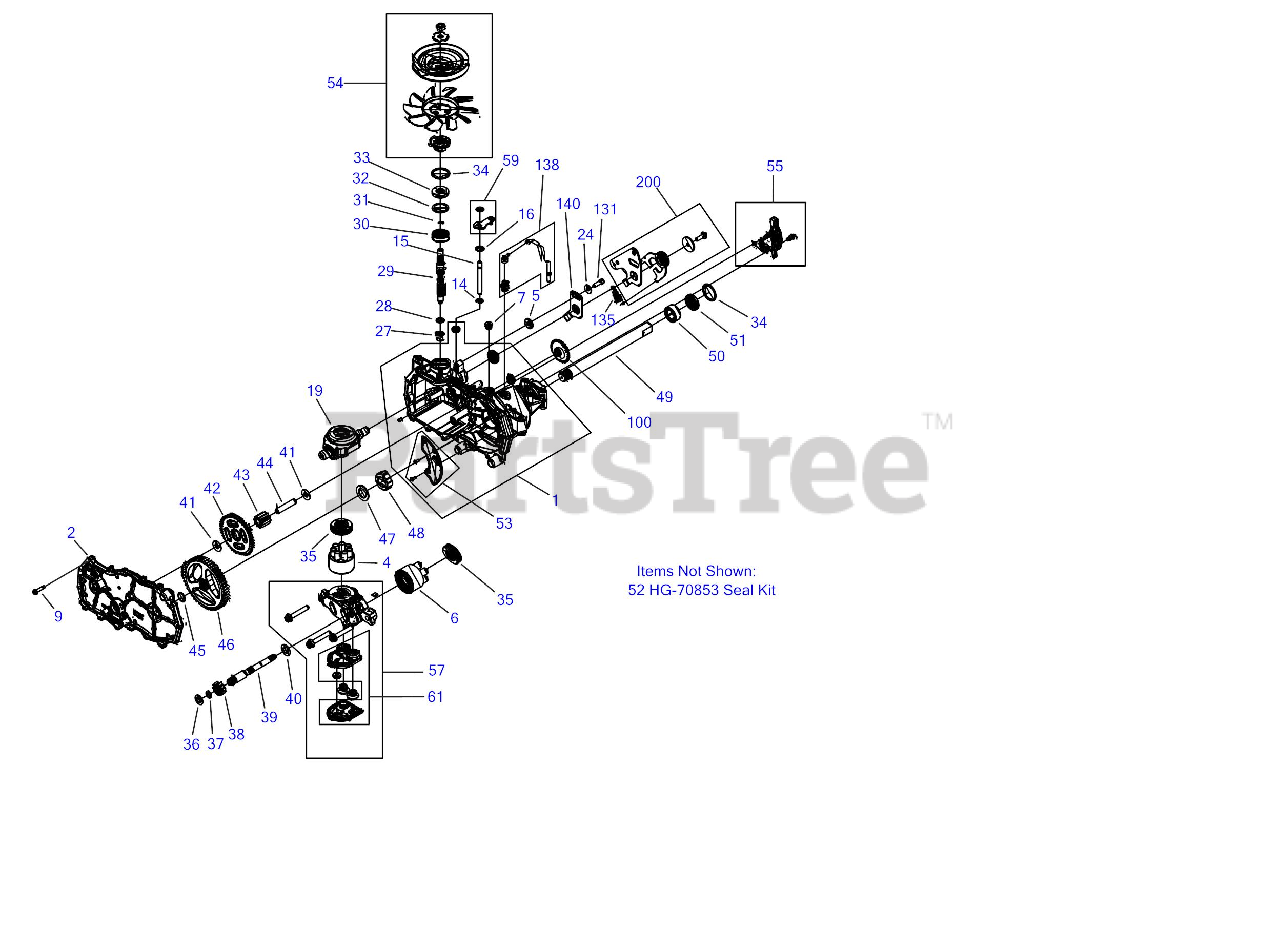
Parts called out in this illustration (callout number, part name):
1	Kit, Housing, Main, RH
2	Kit, Housing, Side, RH
4	Kit, Block, 7 Piston
5	Spacer, .320 x 1.005 x .150
6	Kit, Block, 10cc Cylinder
9	Screw, Hex Washer
14	Ring, Retaining .375 External
15	Rod, Bypass
16	Ring, Ret .375 External
19	Trunnion, Swashplate
24	Washer, .34 x .88 x .06
27	Spring, Block
28	Washer, .59 x .79 x .04
29	Shaft, Input
30	Ball Bearing 17 x 40 x 12
31	Ring, Reatining
32	Washer, 1.23 x 1.57 x .04
33	Seal, Lip 17 x 40 x 7
34	Ring Retaining Internal
35	Thrust Bearing, 30 x 52 x 13
36	Washer, .63 x 1.00 x .05
37	Ring, Reatining, Motor Shaft
38	Gear, 13T Pinion
39	Shaft, Motor
40	Washer, .71 x 1.16 x .04
42	Gear, 10T/48T
43	Gear, 10T Jackshaft
44	Pin, Jackshaft
45	Ring, Spiral Retaining-87
46	Gear, Bull 52T
47	Washer, 1.018 x 1.571 x .105
48	Buahing, Sleeve (Inboard)
49	Shaft, Axle, 1.00 x 11.70 DD
50	Bushing, 1.003 x 1.571 x .625
51	Seal, Lip, TC4, 1.00 x 1.577 x .27
52	Kit, Seals & Rings
53	Kit, Expansion Plate RH
54	Kit, Fan & Pulley
55	Kit, Brake Arm
57	Kit, Center Section RH
59	Kit, Bypass Arm
61	Kit, Filter
100	Disc, Cog Brake
131	Socket Cap Screw, 5/16-24 x 7/8
135	Spring, Extension
138	Kit, Breather
140	Arm, Neutral Right
200	Kit, RTN Bidirectional
